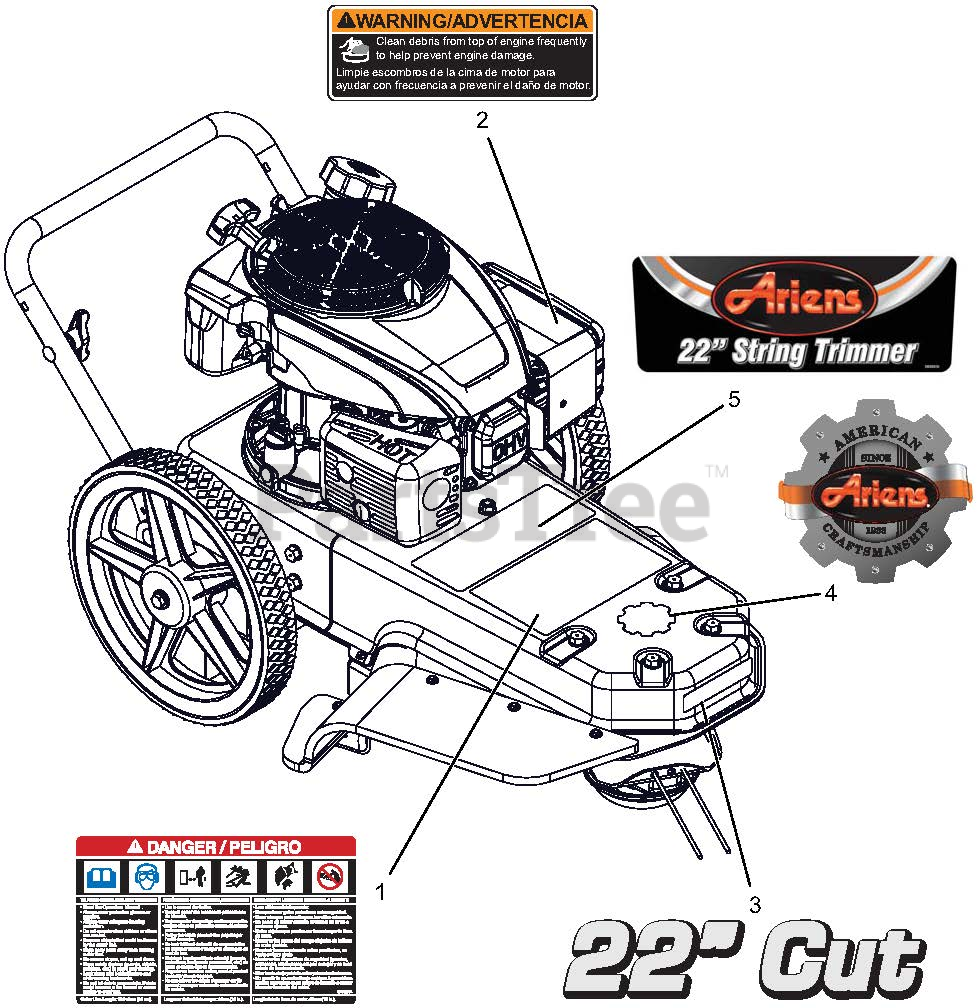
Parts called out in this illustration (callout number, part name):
1	DECAL - DANGER-STRING TRIMMER
2	DECAL, TRIMMER DEBRIS WARNING
3	DECAL, 22" CUT(STRING TRIMMER)
4	DECAL, ARIENS HERITAGE-SMALL
5	DECAL, ARIENS STRING TRIMMER
